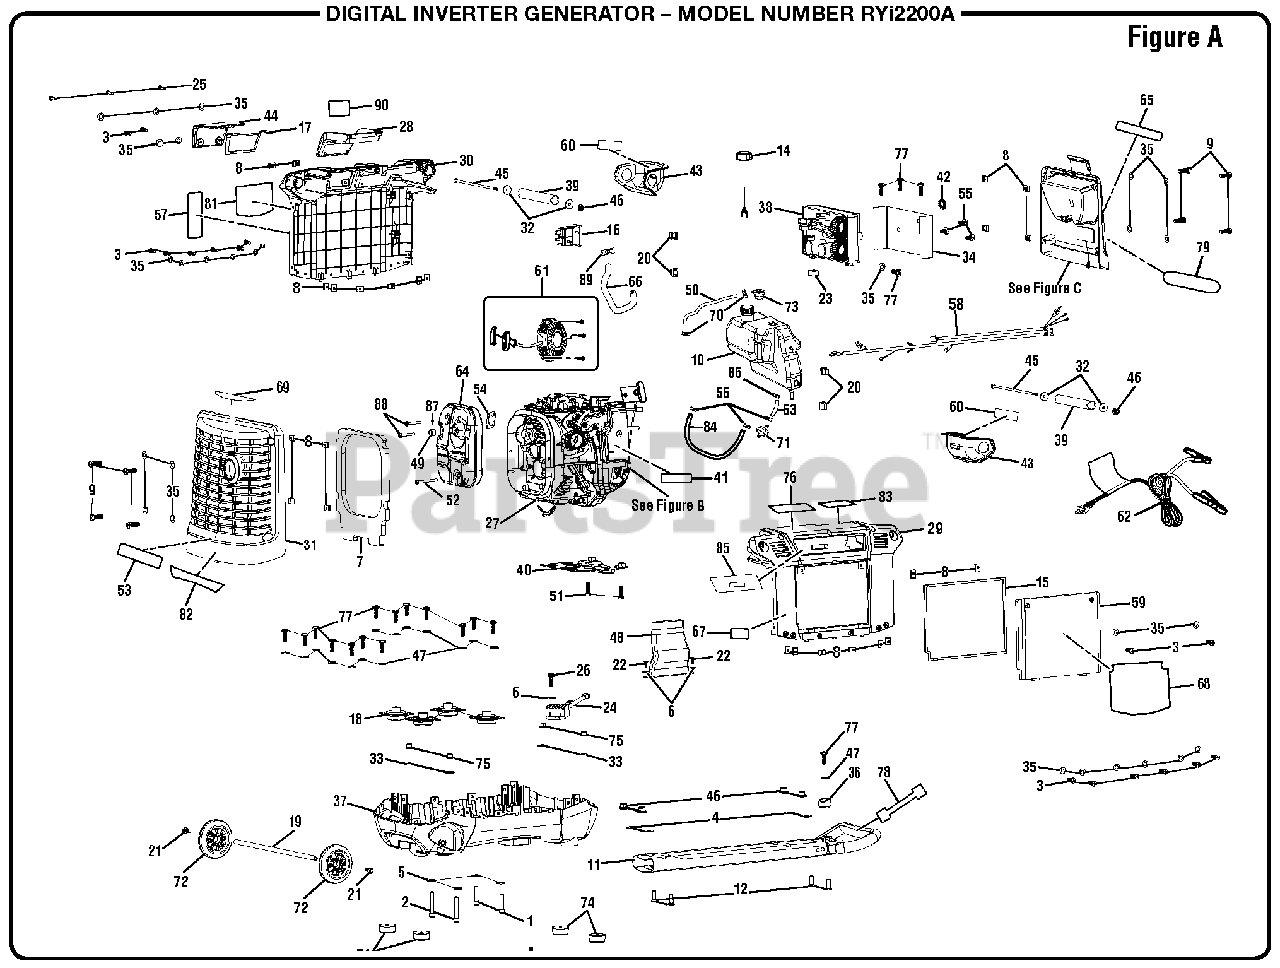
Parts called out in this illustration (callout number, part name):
1	Bolt (M8 x 35 mm, Hex Soc. Hd.)
2	Bolt (M8 x 50 mm, Hex Soc. Hd.)
3	Screw (M5 x 12 mm, Pan Hd.)
4	Washer (ID5.3 x OD15 x 1t)
5	Washer (ID8.3 x OD16 x 2t)
6	Washer (ID4.2 x OD10 x 1t )
7	Foam Pad (Isolator)
8	U-Clip (M5 x 0.8 in.)
9	Screw (M5 x 15 mm, Pan Hd.)
10	Fuel Tank
11	Handle Assembly
12	Screw (M5 x 14 mm, Flat Hd.)
13	Muffler Noise Cover
14	Fuel Tank Cap
15	Seal (Maintenance Cover)
16	Carbon Canister
17	Spark Plug Cover (Foam)
18	Engine Bracket (Isolator)
19	Wheel Axle
20	Support (Fuel Tank)
21	Screw (M6 x 20 mm, Hex Flange Hd.)
22	Screw (M3.5 x 9 mm, Pan Hd.)
23	Base Support
24	Bridge Rectifier
25	Screw (M5 x 30 mm, Pan Hd.)
26	Screw (M4 x 10 mm, Pan Hd.)
27	Engine (106cc Top Sun)
28	Fuel Over spill Guard
29	Left Side Housing w/Labels
30	Right Side Housing w/Labels
31	Muffler Cover
32	Washer (ID6.3 x OD25 x 1.5t)
33	Washer (ID6.3 x OD18 x 1.5t)
34	Air Guide Sheet
35	Washer (ID5.3 x OD10 x0.5t)
36	Handle Bumper
37	Base
38	Inverter Module
39	Handle (Upper)
40	Engine Bracket Assembly
41	Maintenance Label
42	Star Washer
43	Handle Cover
44	Access Cover (Spark Plug)
45	Bolt (M5 x 195 mm, Hex Hd.)
46	Flange Lock Nut (M5 x 0.8 in.)
47	Washer (ID5.3 x OD10 x 1t)
48	Air Filter Duct
49	Spark Arrestor
50	Air Hose (Fuel Tank)
51	Bolt (M8 x 30 mm, Flange Hex Hd.)
52	Bolt (M6 x 65 mm, Flange Hex Hd.)
53	Combustion Label
54	Exhaust Pipe Gasket
55	Bolt (M6 x 12 mm, Hex Hd.)
56	Clamp (D9.5 mm)
57	Danger Icon Label
58	Internal Wire Assembly
59	Maintenance Cover w/Label & Sound Foam
60	Warning Transport w/Handle Label
61	Recoil Starter Assembly
62	DC Cable Assembly w/Label
63	Fuel Hose (50 mm)
65	Logo Label (Small)
66	Air Hose (Carbon Canister To Air Box)
67	Check Oil Label
68	Logo Label (Large)
69	Hot Surface Label
70	Clamp (7 mm)
71	Fuel Filter (1/4 in.)
73	Rollover Vent
74	Rubber Foot w/Metal Insert
75	Flange Lock Nut (M6 x 1 mm)
76	CPSC Label
77	Screw (M4.2 x 12 mm, Pan Hd.)
78	Handle Release Label
79	Ground Warning Label
80	Bolt (M6 x 16 mm, Hex Flange Hd.)
81	Performance Label
82	Fire Distance Label
83	E85 Label
84	Fuel Hose (Fuel Tank To Fuel Pump)
85	Quick Start Label
86	Clamp (10 mm)
87	Screw (M4.2 x 8 mm, Pan Hd.)
88	Bolt (M6 x 45 mm, Hex Flange Hd.)
89	Clamp (8.5 mm)
90	Danger Label
